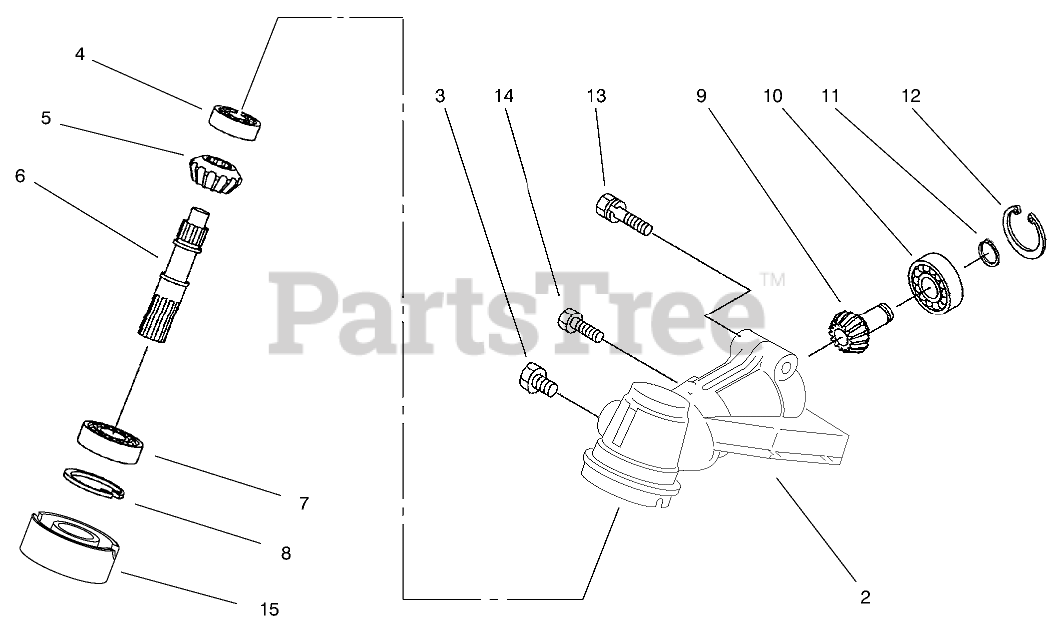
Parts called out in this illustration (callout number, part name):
2	GEAR CASE HOUSING
4	BEARING
5	BEVEL GEAR
6	LOWER SHAFT
7	BEARING
8	RING - SNAP
9	BEVEL GEAR AND SHAFT
10	BEARING
11	RING - SNAP
12	RING - SNAP
15	SPACER-HEAD
